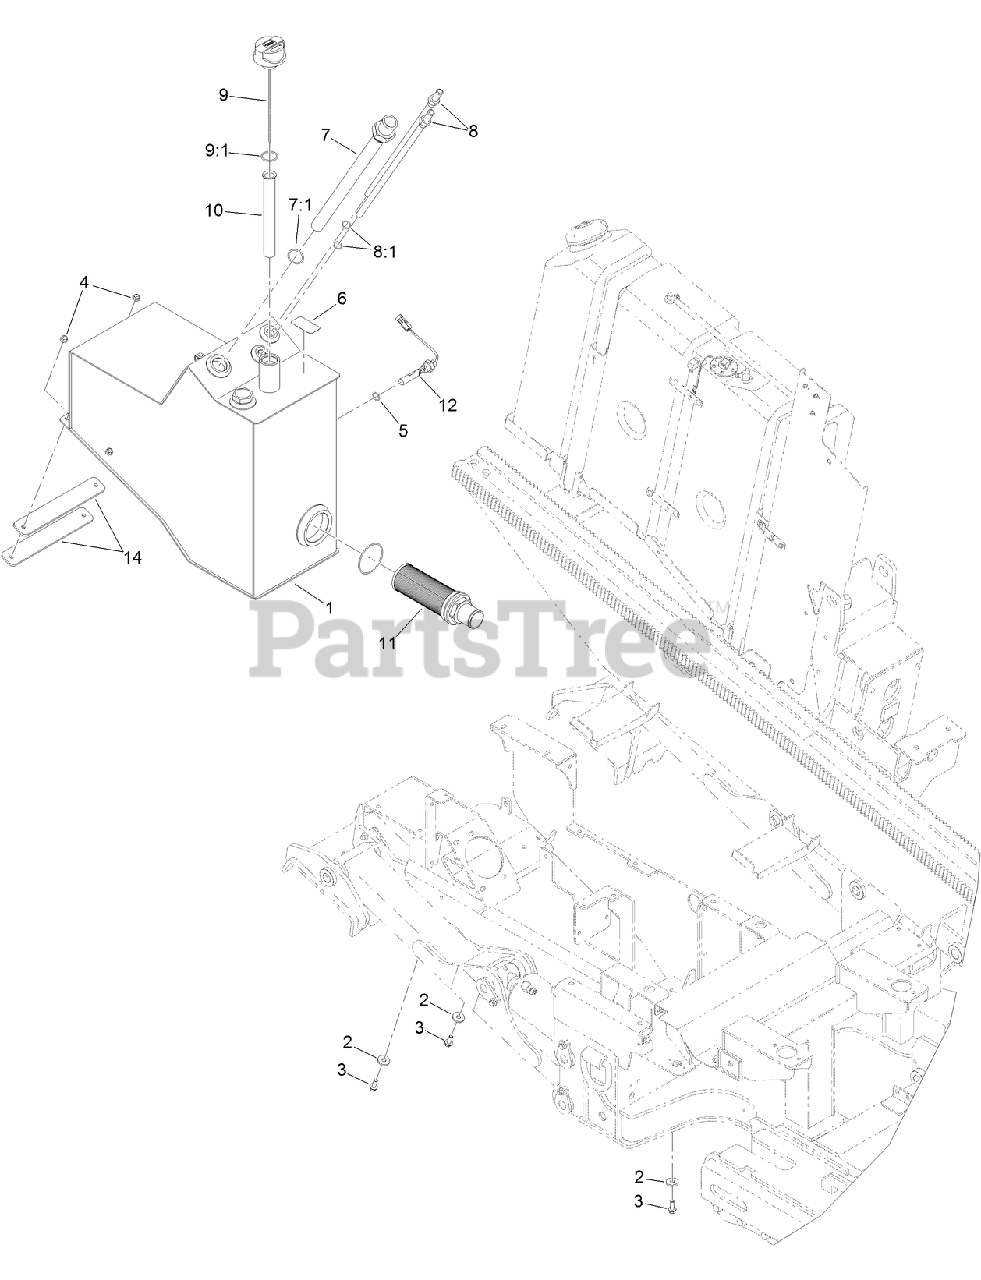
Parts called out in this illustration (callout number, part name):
1	HYDRAULIC TANK ASM
2	SCREW-HHF
3	SCREW-HHF
4	NUT-HF, NI
5	O-RING
6	DECAL-HYD FLUID
7	DROP TUBE ASM
7:1	O-RING
8	DROP TUBE ASM
8:1	O-RING
9	CAP-FILLER, BREATHER
9:1	O-RING
10	SCREEN-FILL, HYDRAULIC
11	STRAINER-SUCTION
12	SENSOR-LEVEL, OIL
14	STRAP-SPACER
